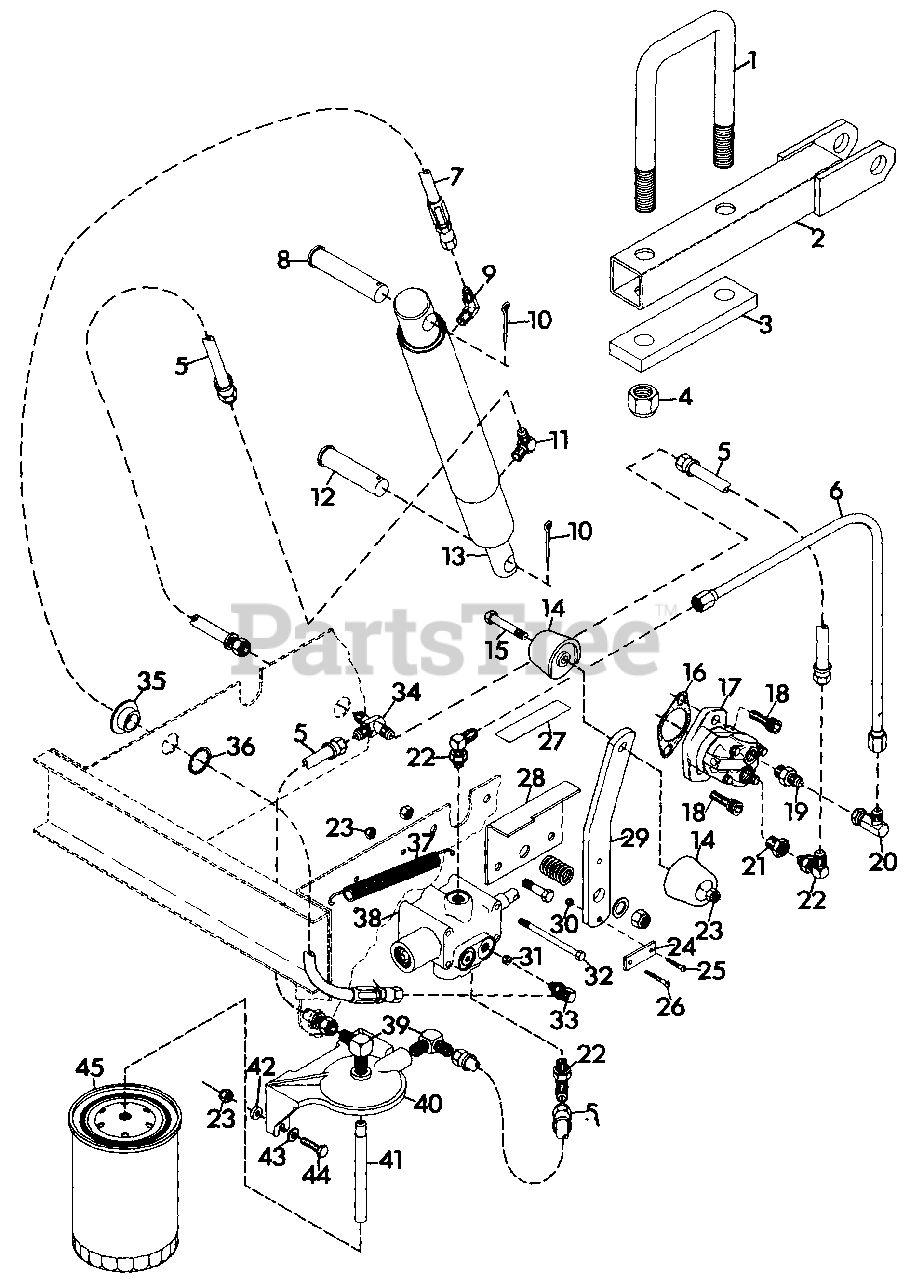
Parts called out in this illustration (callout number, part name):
1	U-BOLT
2	ARM, LIFT
3	PLATE, AXLE
4	NUT, LOCK 5/8-18
5	HOSE, HYDRAULIC
6	LINE, HYDRAULIC PUMP TO VALVE
7	HOSE, HYDRAULIC
8	PIN, CLEVIS
9	ADAPTOR
10	PIN, COTTER .125X1.25
11	ADAPTOR, HYDRAULIC
12	PIN, CLEVIS
13	CYLINDER, HYDRAULIC
14	KNOB, CONTROL
15	BOLT, HEX 1/4-20X1.50
16	GASKET, COVER PLATE
17	PUMP, HYDRAULIC
18	SCREW, CAP 3/8-16 HEX SOCKET HEAD
19	ADAPTOR
20	ADAPTOR
21	BUSHING
22	ADAPTOR
23	NUT, LOCK 1/4-20
24	STRAP, VALVE
25	SCREW, MACHINE 10-24X.75 RD HD
26	SCREW, MACHINE 10-24X1.00 RD HD
27	DECAL, HYDRAULIC LIFT
28	BRACKET, LIFT
29	LEVER, LIFT
30	NUT, LOCK 10-24
31	PLATE, FLOW RESTRICTION
32	BOLT, HEX 1/4-20X2.75
33	ADAPTOR
34	ADAPTOR, TEE
35	BUSHING, NYLON .76X1X.6 FLANGE
36	RING, RETAINING INTERNAL TOOTH
37	SPRING, EXTENSION 5.5X.5X20 RATE
38	VALVE, CONTROL
39	ADAPTOR
40	BRACKET, OIL FILTER
41	TUBE, OIL PICKUP
42	SPACER
43	WASHER, FLAT .312X.734X.065
44	BOLT, HEX 1/4-20X1.25
45	FILTER, SPIN-ON
